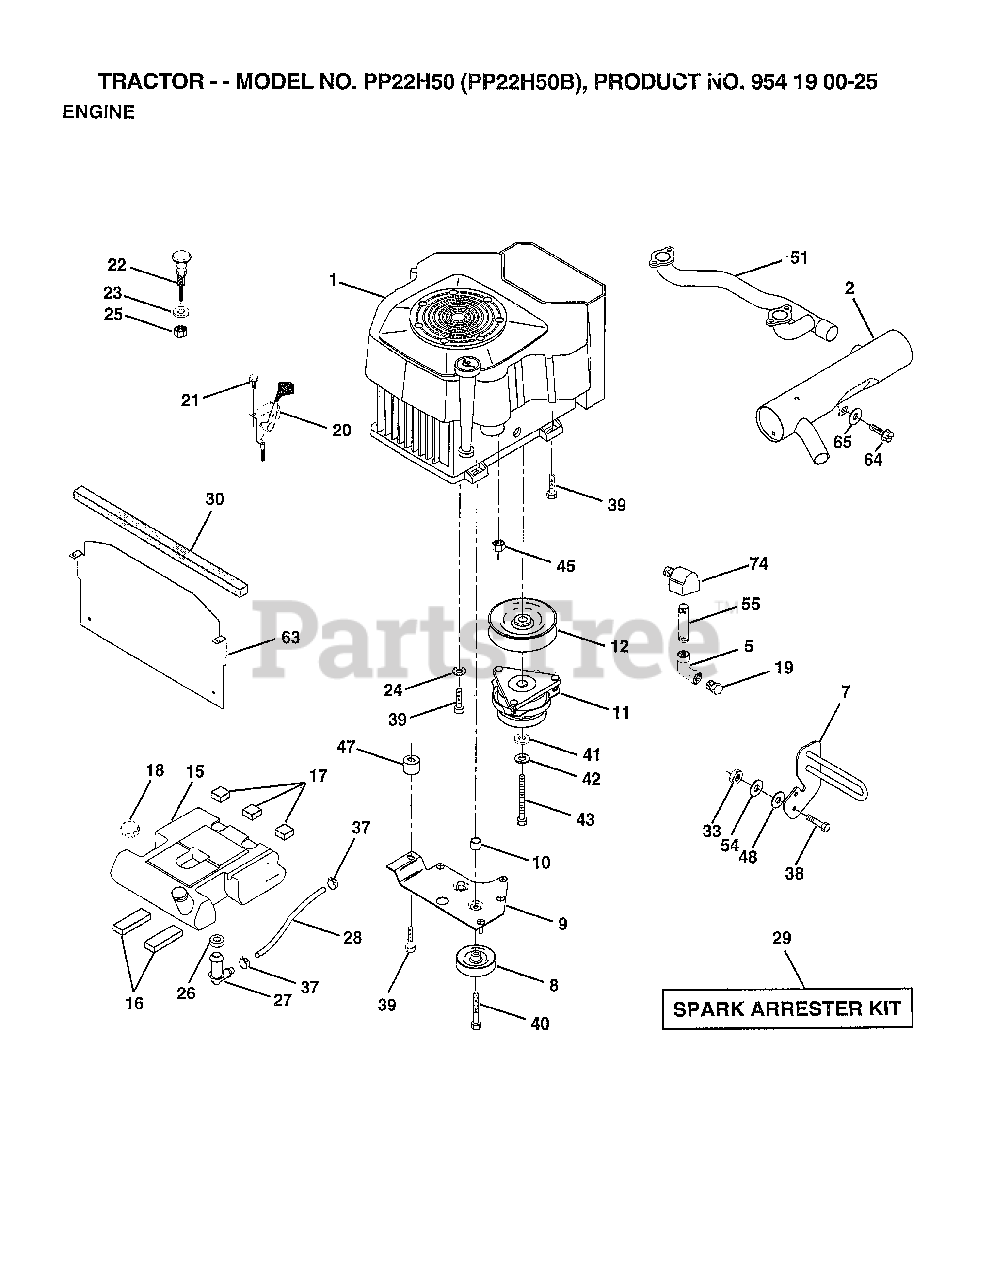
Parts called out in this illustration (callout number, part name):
2	MUFFLER SIDE1-1/8
5	ELBOW
7	GUARD.MUFFLER.ASM
9	KEEPER ASM BELT
10	BUSHING.
12	PULLEY.ENG.CLUTCH
15	TANK FUEL REAR
16	PAD IDLER TI
17	PAD-SPACER LT
18	CAP ASM FUEL
19	PLUG T
21	SCREW LT
22	CHOKE CONTROL
23	WASHER
24	LOCKWASHER
25	"NUT,KEPS 3/8-24IM"
26	BUSHING OUTLET T
27	STEM.TANK.FUEL
29	SPARK ARREST KIT
30	FOAM-STRIP LT
33	NUT
37	HOSE CLAMP
38	"BOLT,HEX"
39	SCREW.3/8-16X2.25
40	SCREW.TT.3/8-16X4
41	WASHER
42	LOCKWASHER
43	BOLT.7/16-20X4.25
45	NUT
47	SPACER.ENGINE
48	WASHER T
51	MANIFOLD PIPE VGT
54	WASHER
55	PIPE NIPPLE LT
63	HEAT.SHIELD.VGT.
64	SCREW THDROL 3/8-16
65	WASHER
74	ELBOW STREET BASS
